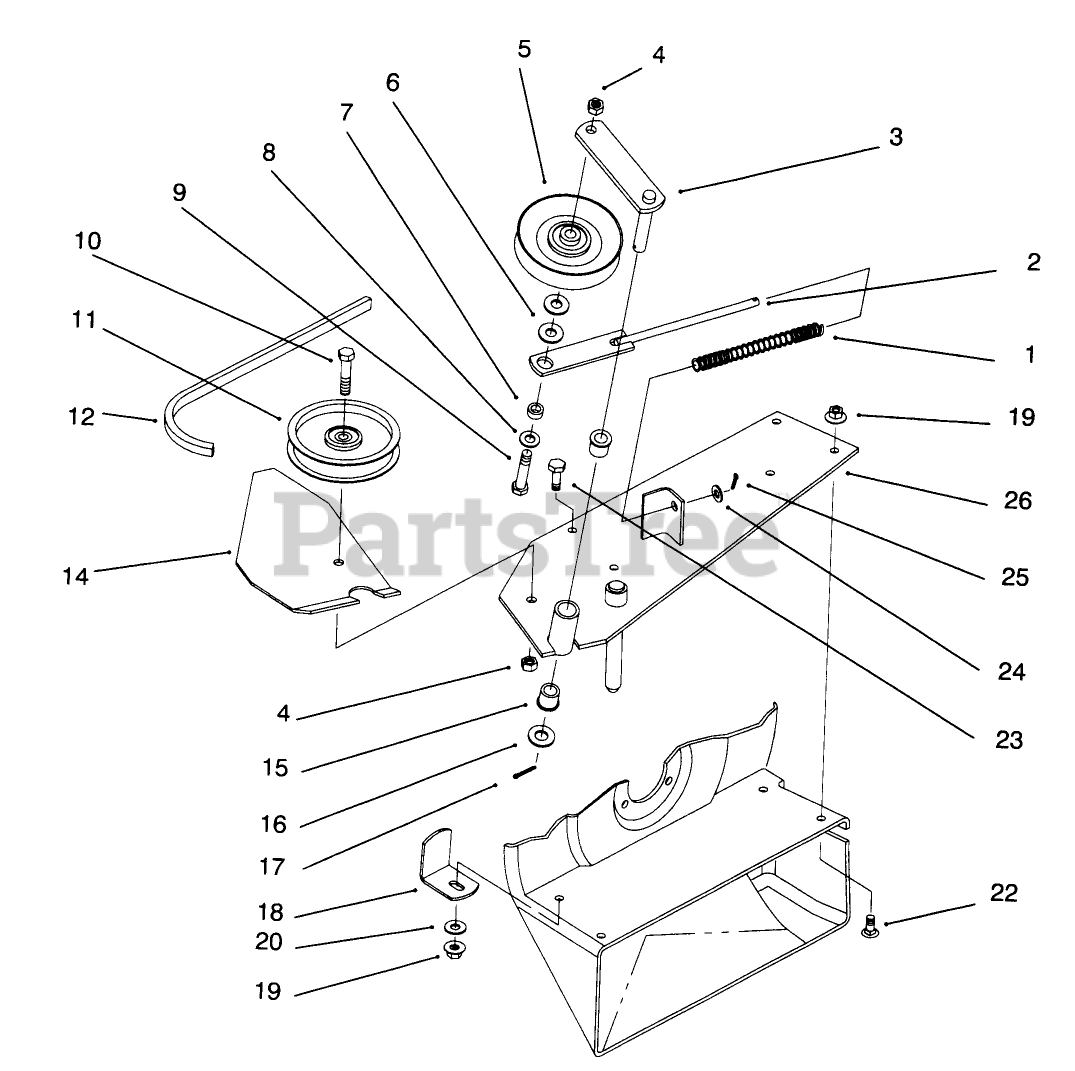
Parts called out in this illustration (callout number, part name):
1	SPRING-COMPRESSION
2	SPRING-ROD
3	IDLER ARM ASM
4	NUT-LOCK, NI
5	PULLEY-IDLER
6	WASHER-FLAT
7	SPACER
8	WASHER-FLAT
9	SCREW-HH
10	SCREW-HH
11	PULLEY-IDLER
12	V-BELT
14	SHIELD SUPPORT B
15	BUSHING
16	WASHER-FLAT
17	PIN-COTTER
18	BRACKET-SUPPORT, HOUSING
19	NUT-HF
20	WASHER-FLAT
22	BOLT-CARR
23	SCREW-HH
24	WASHER-PLAIN
25	PIN-COTTER
26	BLOWER-MTG ASM
